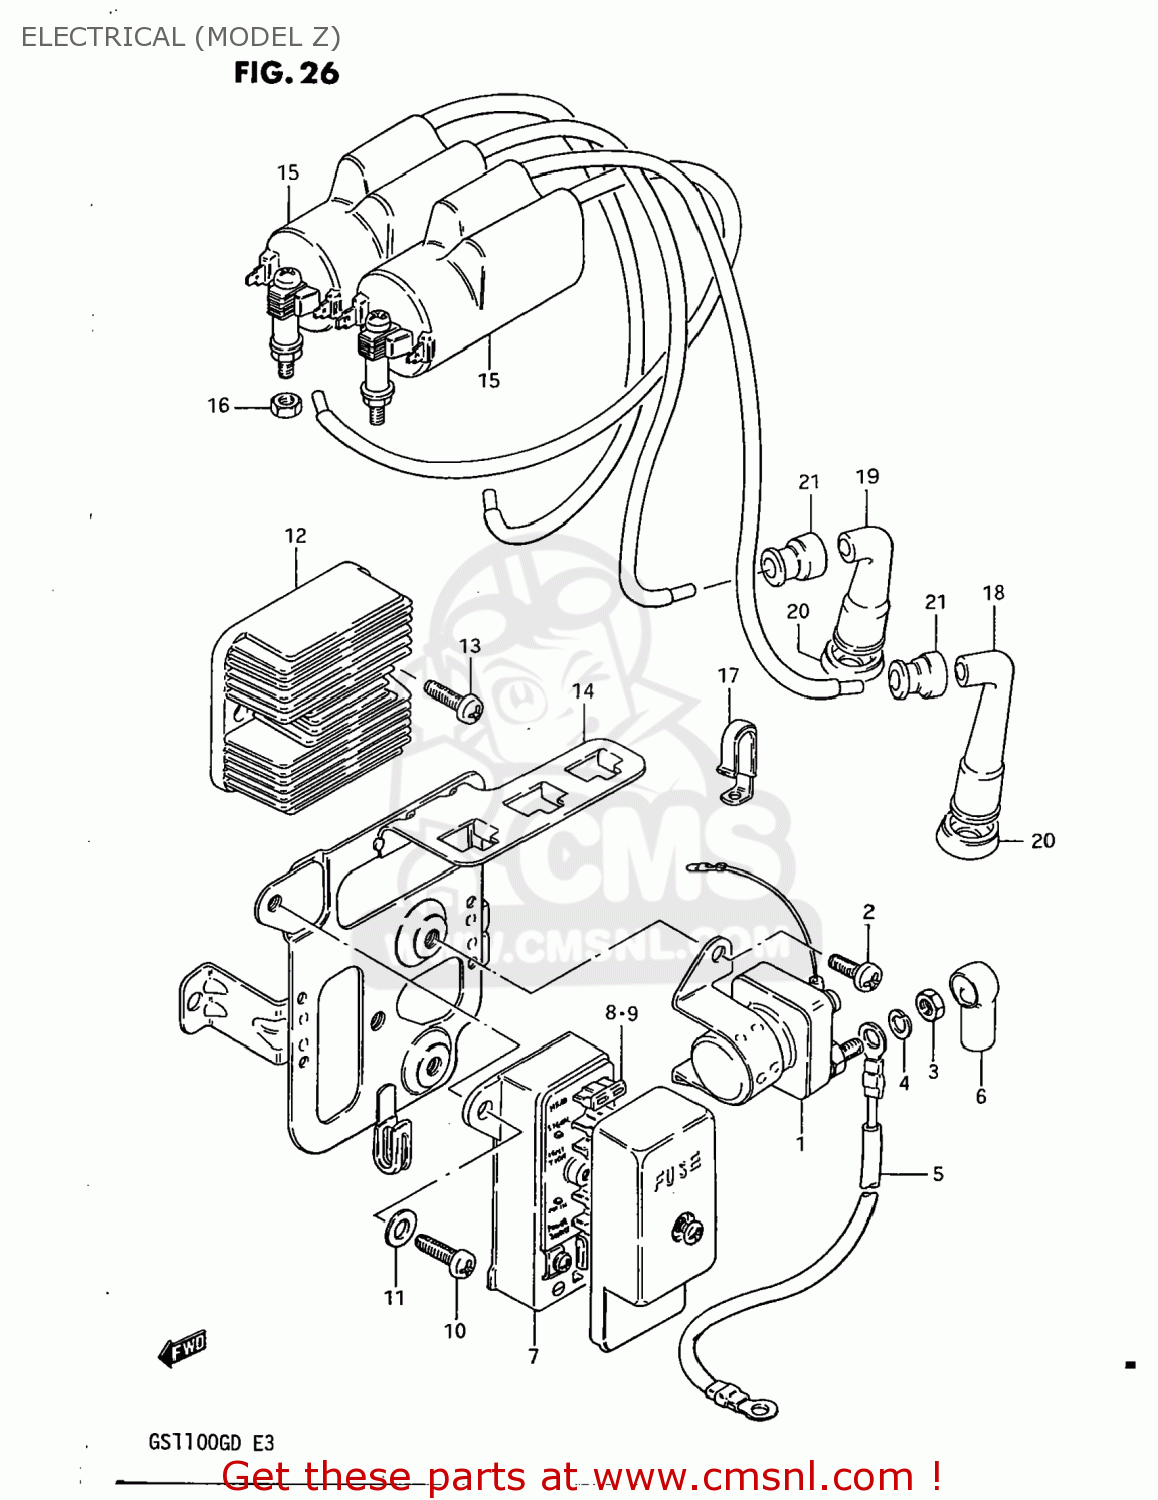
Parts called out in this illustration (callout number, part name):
1	RELAY ASSY,STARTING MOTOR
2	SCREW
3	NUT 6MM
4	LOCK WASHER
5	CABLE,STARTING MOTOR
6	CAP,STARTER RELAY
7	BOX ASSY,FUSE
8	FUSE(10A)
9	FUSE(15A)
10	SCREW 6X12
11	WASHER
12	RECTIFIER ASSEMBLY
13	SCREW 6X12
14	HOLDER COMP,ELECTRONIC PARTS
15	COIL ASSEMBLY,IGNITION
16	NUT
17	CLAMP
18	CAP ASSY,SPARK PLUG
19	CAP,SPARK PLUG
20	SEAL,SPARK PLUG
21	SEAL,SPARK PLU
